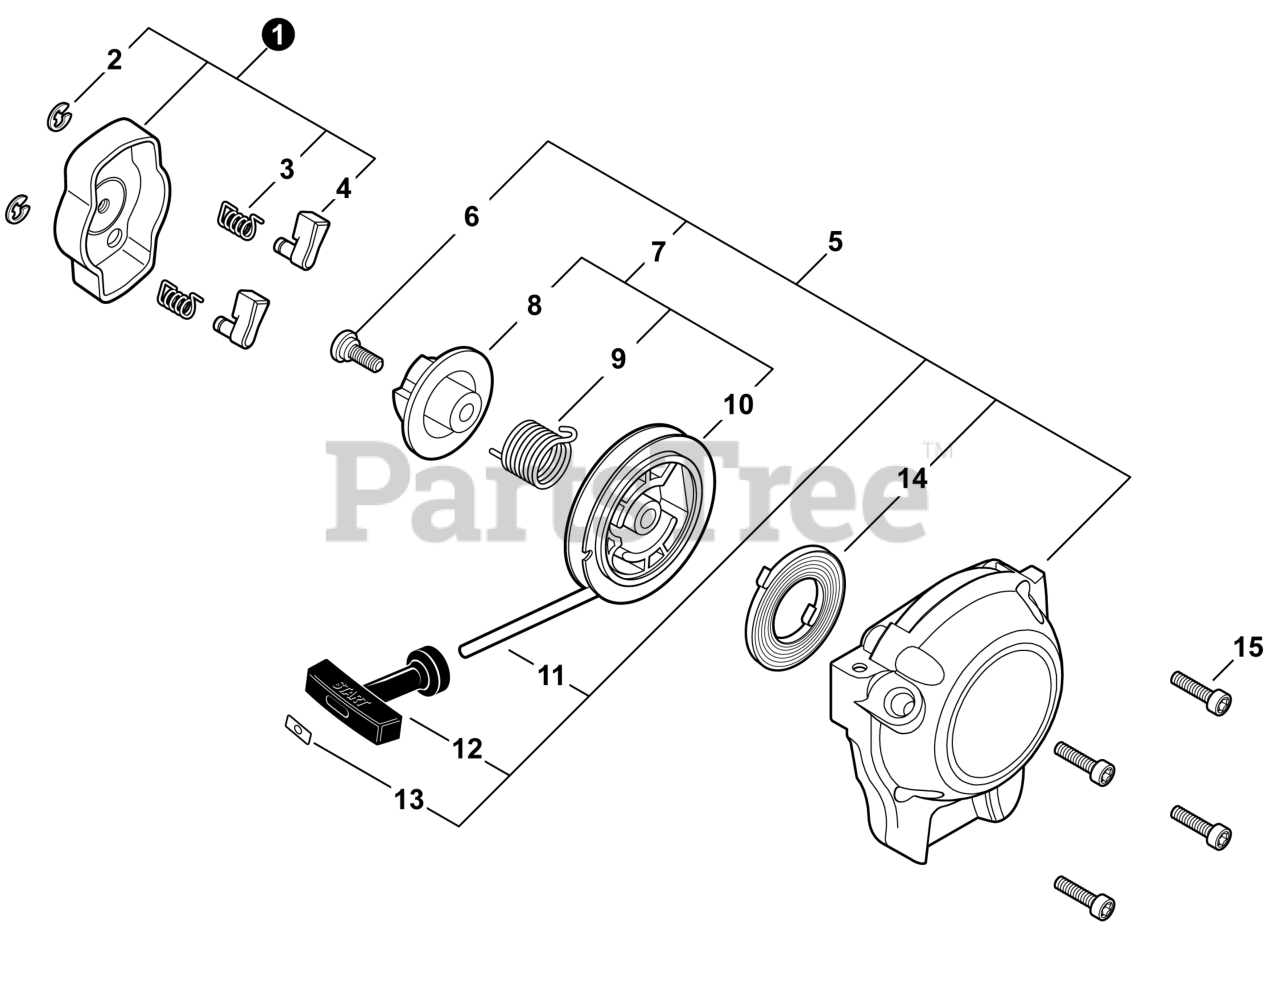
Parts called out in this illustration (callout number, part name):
1	PAWL ASSY, STARTER
2	E-RING 4
3	SPRING, RETURN
4	PAWL, STARTER
5	STARTER ASSY, RECOIL
6	SCREW 5
7	REEL/CAM PLATE SET
8	PLATE, CAM
9	SPRING, TORSION
10	REEL, ROPE
11	ROPE, STARTER 3x700
12	GRIP, STARTER
13	RETAINER, ROPE
14	SPRING, RECOIL
15	BOLT, TORX 4x16
